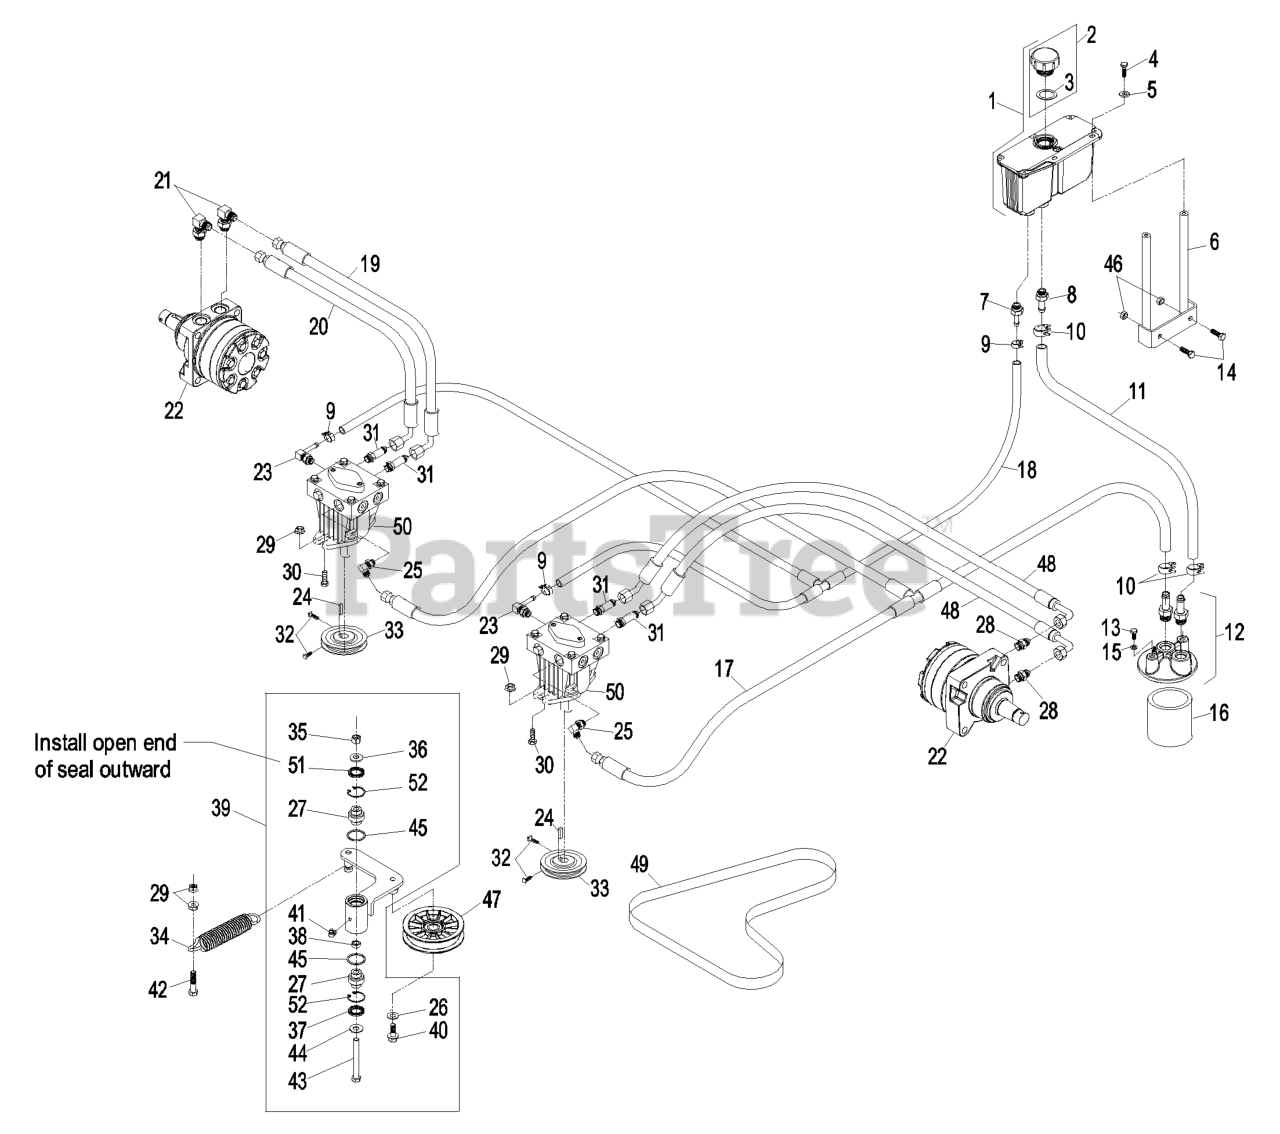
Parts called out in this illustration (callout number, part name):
1	HYD RESERVOIR ASM
2	KIT,HYD RES CAP W/GASKET
3	GASKET-CAP
4	SCREW-HH
5	WASHER-FLAT
6	STAND-RESERVOIR
7	ADAPTER-STRAIGHT
8	ADAPTER-STRAIGHT
9	CLAMP-HOSE
10	CLAMP-HOSE
11	HYD HOSE ASM
12	FILTER HEAD ASM
13	SCREW-HH
14	SCREW-HH
15	WASHER-LOCK
16	FILTER-25 MICRON, BI-DIRE
17	HYD HOSE ASM
18	HYD HOSE ASM
19	HOSE,HYDRAULIC
20	HOSE,HYDRAULIC
21	FITTING-HYD, 90 DEG
22	MOTOR-WHEEL
23	ELBOW-90 DEG
25	FITTING-ELBOW, 90 DEG
26	WASHER-FLAT
27	BEARING-SPHERICAL
28	FITTING-STRAIGHT
29	NUT-HHF, WHIZ
30	SCREW-HH
31	ADAPTER-STR, LONG
32	SCREW-SET
35	NUT-LOCK, NI
36	WASHER-BELLEVILLE
37	SEAL-LIP, DOUBLE
39	KIT, PUMP IDLER LHP/LCT
40	SCREW-HHF
41	FITTING-GREASE, 90 DEG
42	SCREW-HH
43	SCREW-HH
44	WASHER-FLAT
47	PULLEY-IDLER, FLAT
48	HOSE,LH 52
49	BELT
50	PUMP-HYD
51	SEAL-LIP, SINGLE
52	RING-SNAP
